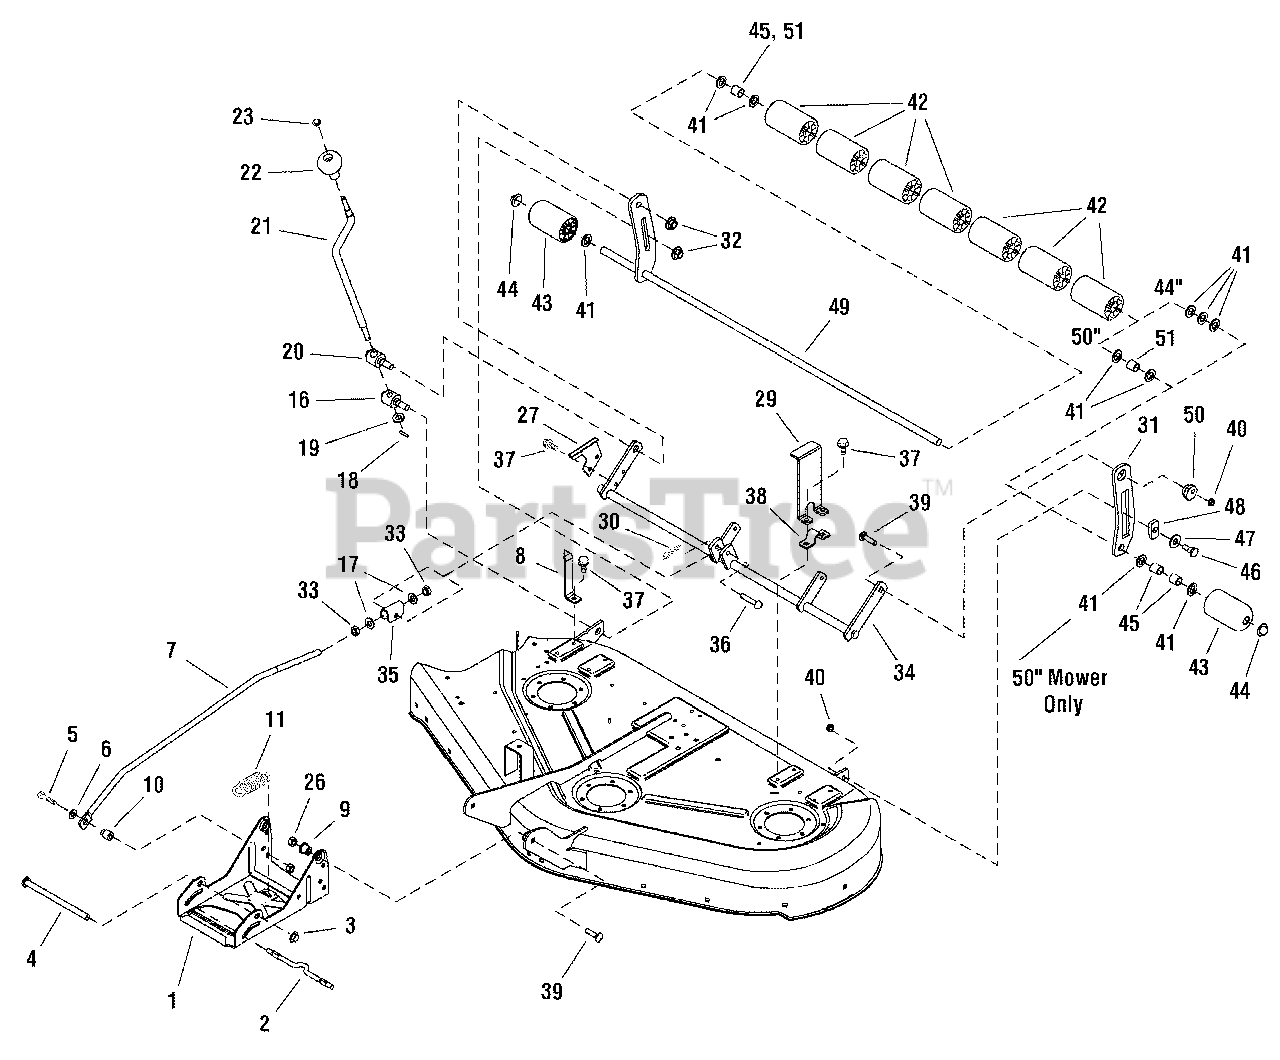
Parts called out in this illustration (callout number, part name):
1	HITCH, Mower 7GA
2	ROD, 3/8 Diameter
3	NUT, Push for 1/2 Diameter Stud Capped
4	ROD, 1/2 Diameter
5	CAPSCREW, Hex Head 3/8-16 x 1-3/4 G8
6	WASHER, 3/8
7	ROD, 1/2 Diameter E-Coat
8	INDICATOR, Height
9	SPACER, Powedered Metal
10	SPACER, 3/8 x 3/4 x 15/16
11	SPRING, Extension
16	TRUNNION, 1-1/4
17	WASHER, 1/2
18	PIN, Spring
19	WASHER, Detent
20	TRUNNION, 1-1/4
21	CRANK, Height Adjusting
22	KNOB, Spinner
23	NUT, Push Pal 3/8 Diameter Stud Capped
26	NUT, Hex Flange 3/8-16 ESNA
27	BRACKET, Height of Cut 16GA
28	SCREW, Hex Washer Head Taptite 5/16-18 x 5/8
29	UPSTOP, 7GA
30	CLIP, Hair Pin
31	BAR, Roller Square Slot
32	NUT, Hex Flange 1/2-13 Two-Way Lock
33	NUT, Hex Jam 1/2-13
34	SHAFT ASSEMBLY, Rocker 44"
34	SHAFT ASSEMBLY, Rocker 50"
35	TRUNNION
36	PIN, Round Head Drilled 3/8 x 2
37	SCREW, Hex Washer Head Taptite 5/16-18 x 3/4
38	STRAP, Roller E-Coat
39	CARRIAGE BOLT, 3/8-16 x 1-1/2 G5
40	NUT, Hex Toplock Spiral Lock Flange 3/8-16
41	WASHER, 5/8
42	ROLLER
43	ROLLER, Rounded
44	NUT, Push for 5/8 Diameter Stud Capped
45	SPACER, Split
46	BOLT, Shoulder 3/8-16 G5
47	WASHER, 1/2
48	SLIDE
49	SHAFT ASSEMBLY, Roller 44"
49	SHAFT ASSEMBLY, Roller 50"
50	NUT, Hex Adjusting Powdered Metal
51	SPACER
